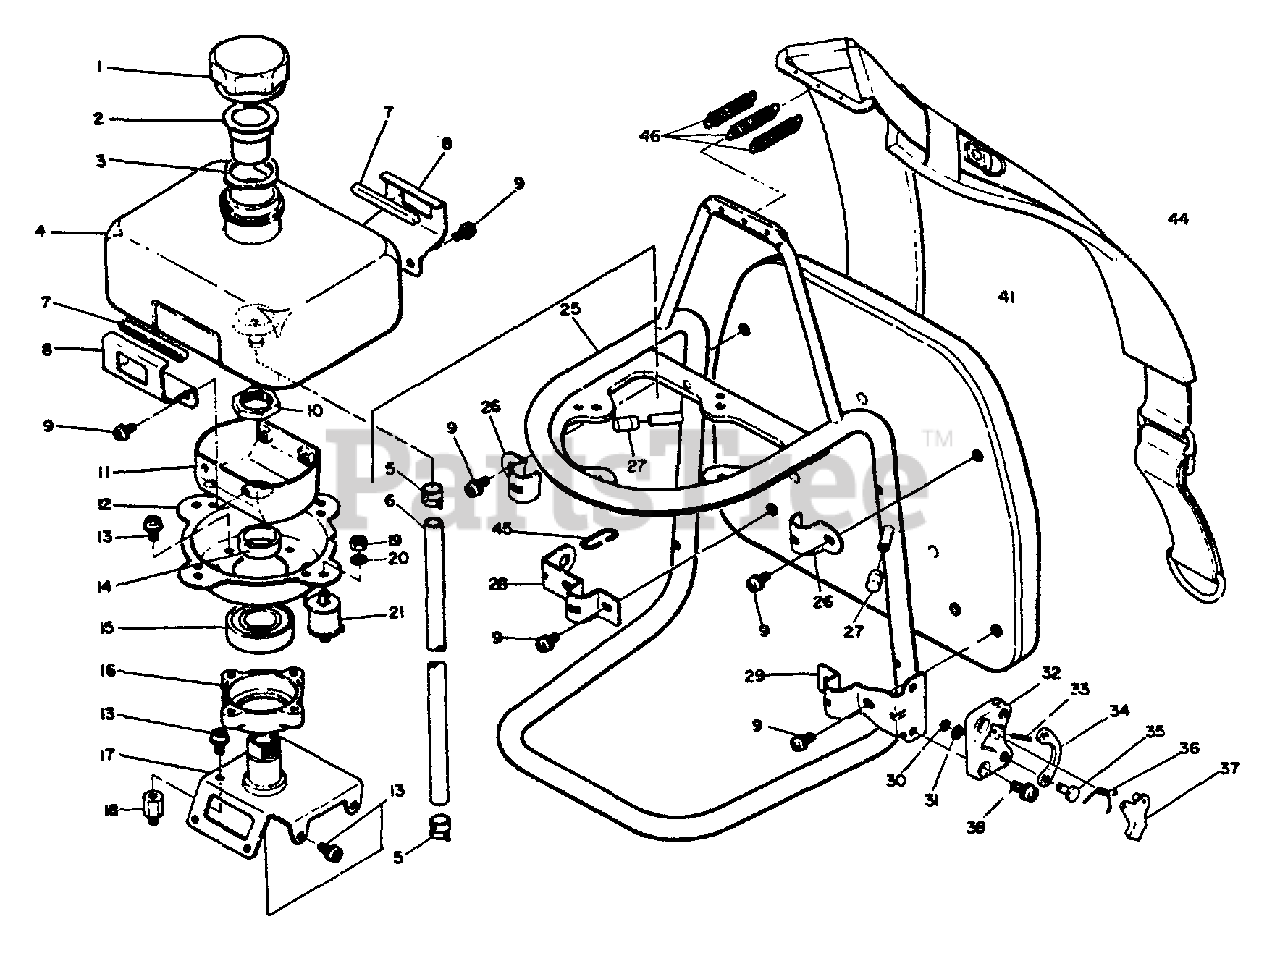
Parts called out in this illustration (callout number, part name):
1	CAP
2	VENT, CAP
3	GASKET, CAP
4	TANK, FUEL
5	CLAMP
6	PIPE - FUEL
7	CUSHION, FUEL TANK
8	BRACKET, FUEL TANK
9	SCREW - 5X10
10	NUT
11	ADAPTER, FUEL TANK
12	CASE, FUEL TANK ADAPTER
13	SCREW - 5X12
14	SPACER
15	BEARING, BALL - 6004
16	CASE, BEARING
17	SHAFT ASSY
18	NUT
20	LOCKWASHER - 5
25	FRAME, BACKPACK
26	BRACKET, CUSHION
27	STOPPER
28	BRACKET, FAN COVER
29	BRACKET, CUSHION
30	RING, RETAINING - 4
31	WASHER - 5
32	BRACKET
33	PIN - SPRING -- 3X20
34	ARM, DETACHING
35	PIN
36	SPRING
37	LEVER, DETACHING
38	SCREW - 5X12
41	CUSHION
44	BACKPACK STRAP ASSY
45	RING, STRAP
46	SPRING
